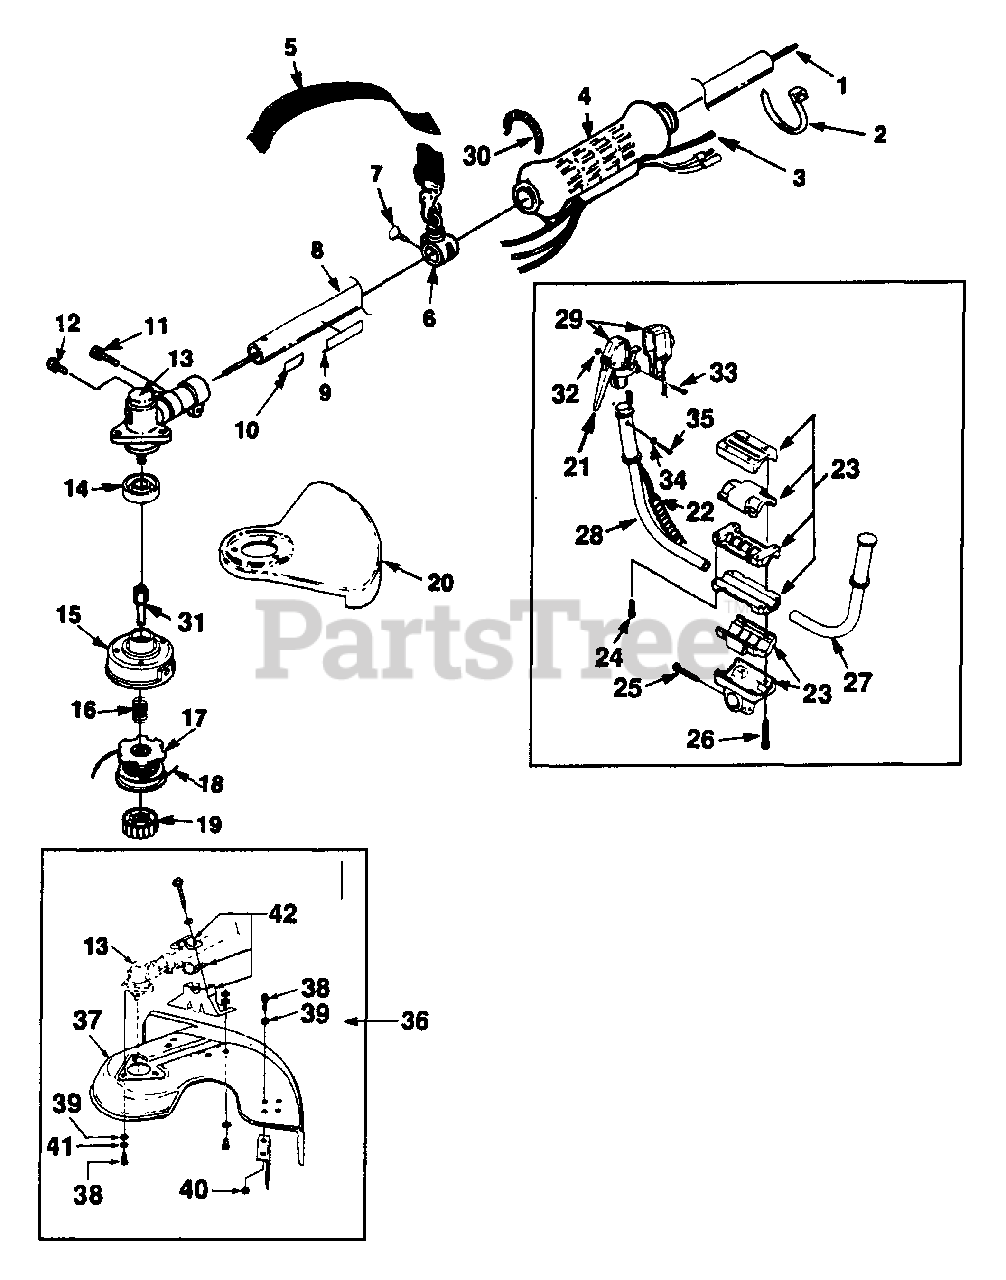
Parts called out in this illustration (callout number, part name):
1	DRIVESHAFT
2	CABLE-Tie
3	THROTTLE CABLE
4	GRIP-Handle
5	HARNESS w/Connector
6	BRACKET-Hanger
7	SCREW-Thumb (10-24 X 1/2")
8	HOUSING-Driveshaft
9	DECAL-Starting Inst.
10	DECAL-Warning
11	SCREW-Cap Socket Hd. (10-24 X 1")
12	SCREW-Sems Hex Hd. (10-24 X 1/2")
13	GEAR HEAD
14	WASHER-Flanged
15	HOUSING & EYELET
16	SPRING-Compression
17	SPOOL & STRING
18	LINE-Replacement (.095 Dia)
19	SPOOL RETAINER
20	GUARD-Blade
21	THROTTLE
22	SLEEVING-Plastic
23	BRACKET-Handle Bar
24	SCREW-Soc. Hd.
25	SCREW-Hex Hd.
26	SCREW-Hex Hd.
27	HANDLE BAR & GRIP (Left)
28	HANDLE BAR & GRIP (Right)
29	SWITCH & LEAD
30	SPRING-Torsion
31	CONNECTOR-Drive
32	NUT (4M)
33	SCREW (4M)
34	WASHER-Lock
35	SCREW-Thread Form. (#6-19 x 3/4")
36	GRASS DEFLECTOR KIT
37	DEFLECTOR & BLADE
38	SCREW
40	NUT (10-24)
42	DEFLECTOR BRACKET KIT
